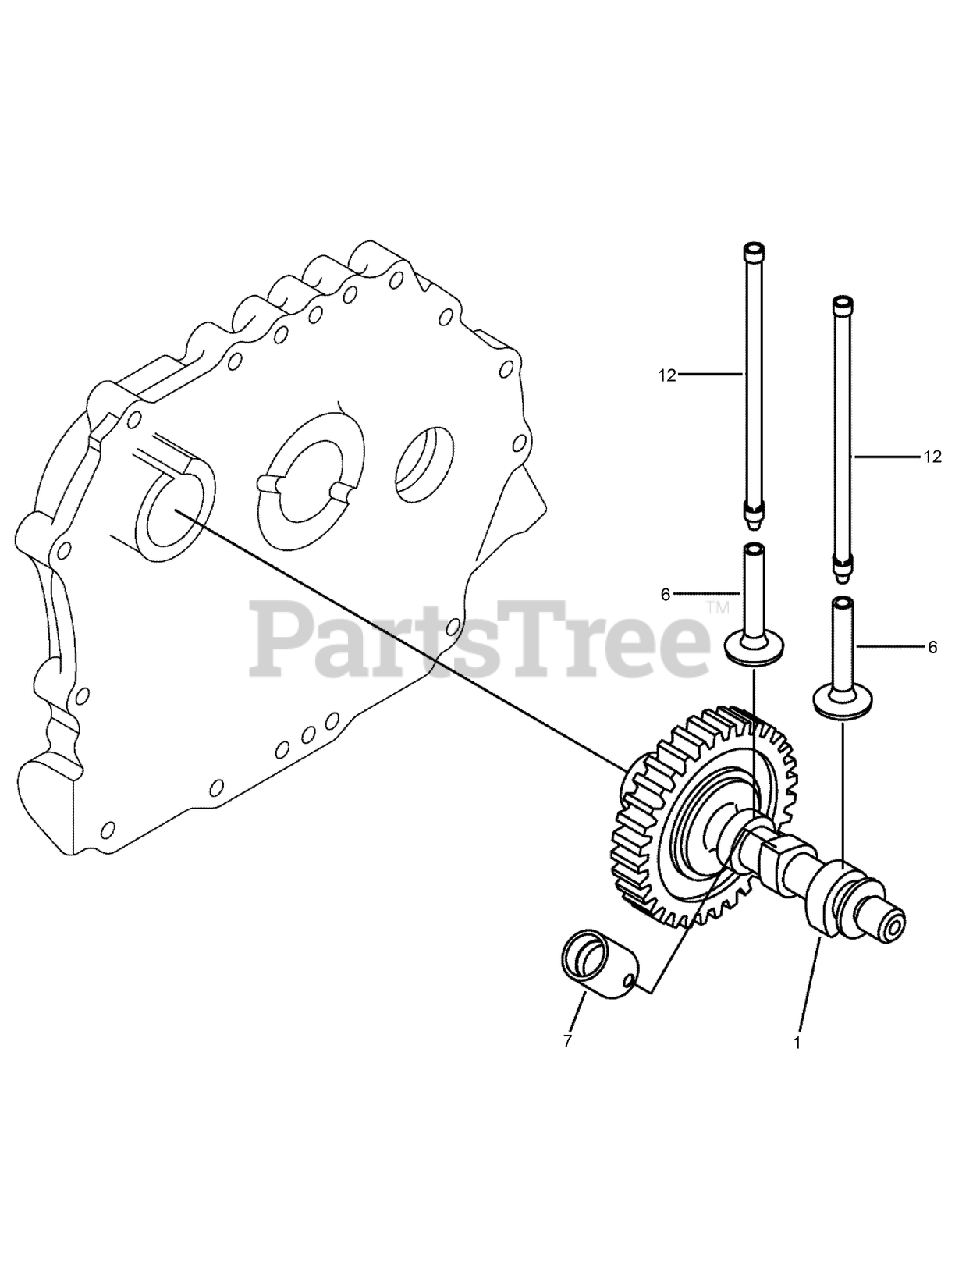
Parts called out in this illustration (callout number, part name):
1	CAMSHAFT ASM
6	TAPPET
7	TAPPET ROLLER ASM
12	PUSH ROD ASM
